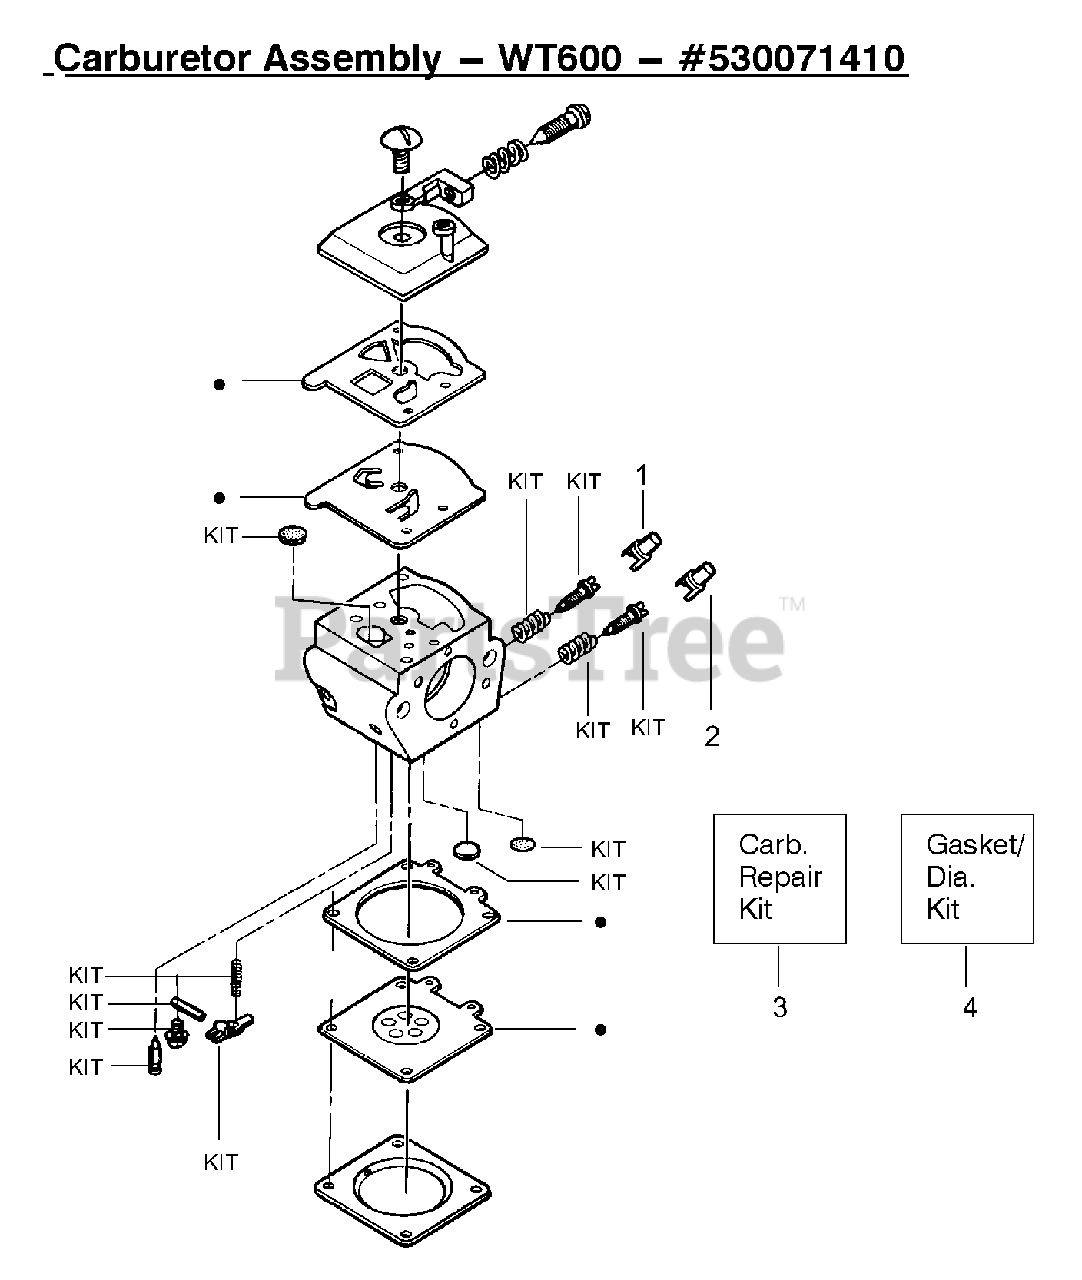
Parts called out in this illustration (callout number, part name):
1	Limiter Cap-High
2	Limiter Cap-Low
3	Carburetor Repair Kit
4	Gasket Diaphragm Kit
530071410	Carburetor Assembly - WT600
